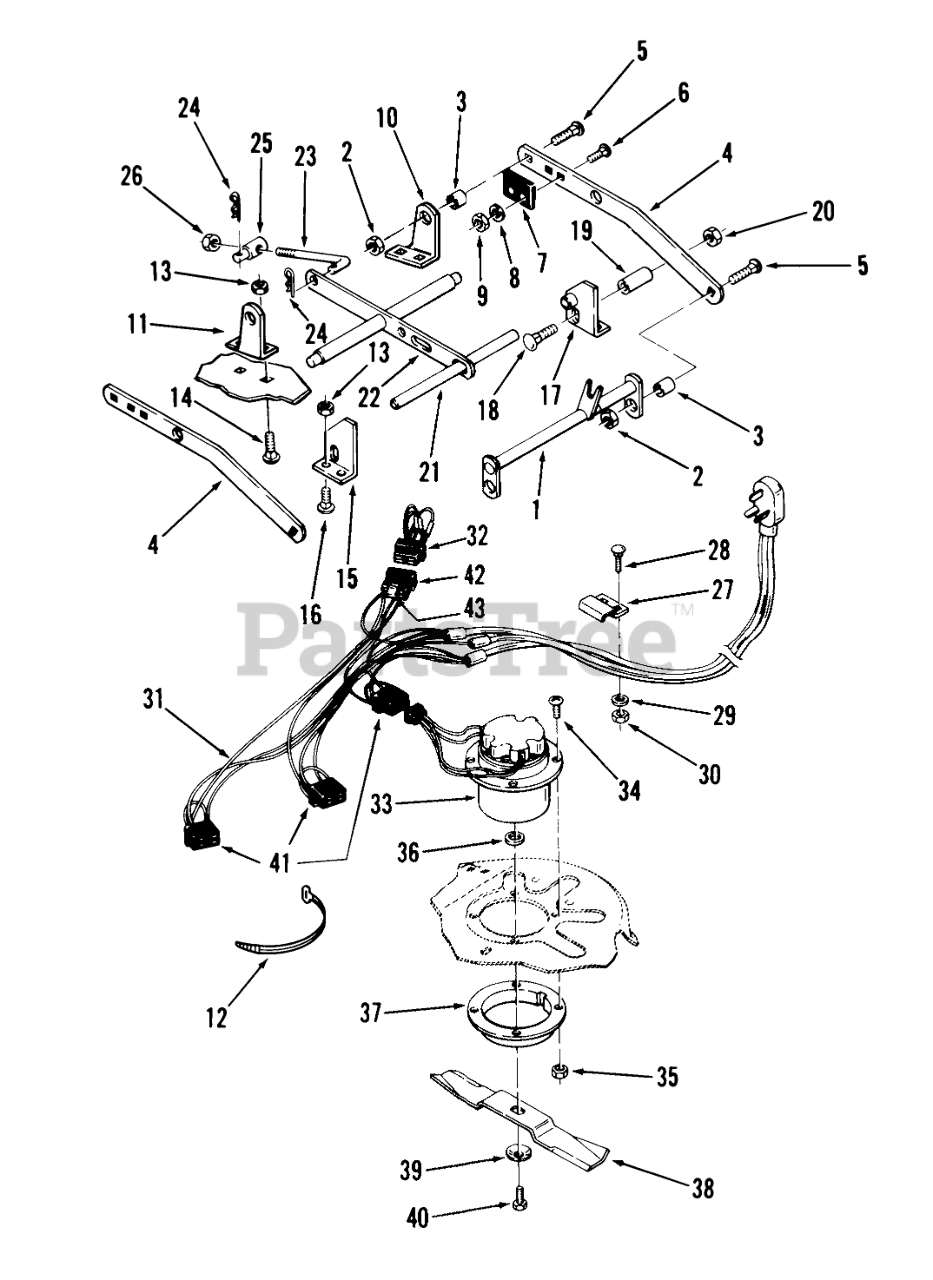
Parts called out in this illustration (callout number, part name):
1	Hitch
2	LOCKNUT-FLANGE
3	SPACER
4	Bar Draft
5	Bolt
6	Bolt-Carriage
7	BUMPER
8	Collar
9	Nut
10	LH Rear Bracket
11	Rear Bracket RH
12	Cable Tie
13	Nut
14	Bolt-Carriage
15	Front Bracket RH
16	Bolt-Carriage
17	Front Bracket LH
18	CARRIAGE BOLT -4
19	SPACER-BEARING
20	Nut
21	Front Shaft
22	Leveler
23	ROD-LEVEL ADJUST
24	Hairpin
25	TRUNNION-LIFT
26	NUT
27	Cable Clamp
28	Bolt-Hex
29	WASHER
30	Nut
31	Wiring Harness
32	Resistor Module
33	Mower Motor
34	Screw
35	Nut
36	Neoprene Washer
37	Flange
38	Blade Kit-Set of 3
39	Spring Washer
40	H H C S
41	4-CONTACT CONNECTOR
42	Connector Body
43	Clip Resistor Plug
